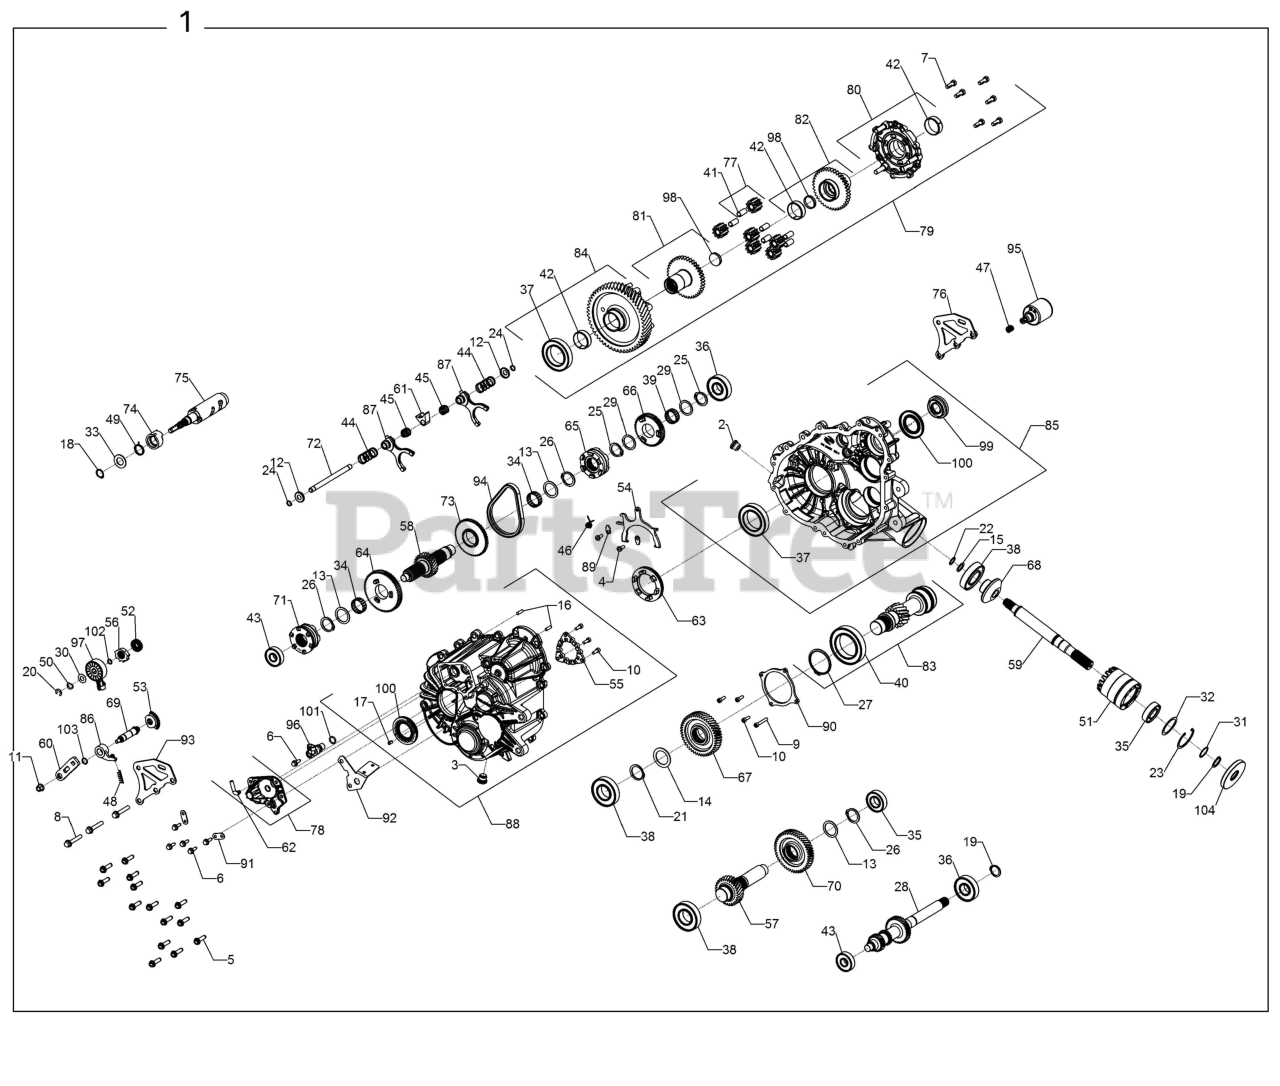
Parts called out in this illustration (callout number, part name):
1	ASM., MAIN GEARCASE
2	PLUG-SKT HD 1SO 6149,M18 X 1.5
3	PLUG-SOCKET HEAD W/MAG,M18X1.5
4	SCREW, TORX PAN HD M6 X 1 X 16
5	SCREW-HEXFLANGEHEAD,M8X1.25X30
7	SCREW-CAP HH,M8 X 1.25 X 20
9	SCR-M6X1.0X40,SOC/CAP(105344)
10	SCR-SCKT HD,CP,M6X1X18(105355)
11	NUT-M8X1.25,HXFLG,NYLN(110093)
12	WASHER-CUP
16	PIN, DOWEL, 6 X 20
17	SPRING-SLOTTED PIN,6MM
18	RING, RETAINING BASIC EXTERNAL
19	RING, SNAP
20	RING-RETAINING
21	RING,RETAINING
22	RING,RETAINING,EXTERNAL SHR-66
23	RING,RETAININGBASICINTRNL2.047
24	RING-RETAINING
25	RING,RETAINING
26	RING, RETAINING, EXTERNAL
27	RING, RETAINING
28	SHAFT-PINNION,INPUT,BOSS,LW
29	WASHER,THRUST
30	WASHER,THRUST,.446X.88X.025
31	SHIM 1.180 X .995
32	SHIM 2.040 OD X 1.630 ID
33	SPACER, 19.4 X 34 X 2
34	BEARING,NEEDLE
37	BEARING, BALL
38	BEARING-BALL
39	BEARING,NEEDLE
40	BEARING, BALL
41	BEARING,PLAIN,10X12X25
42	PLAIN,BEARING 40X44X15
43	BEARING, BALL
44	SPRING-COMPRESSION
45	SPRING-COMPRESSION
46	SPRING, TORSION RETURN
47	SPRING,COMPRSSN.54ODX.44IDX.05
48	SPRING, COMPRESSION DETENT
49	SPRING, TORSION
50	WASHER-SPRING,210393
51	TUBE, SNORKLE MACH
52	GEAR-SECTOR,16T
53	GEAR-SECTOR,31T-CUT TO 11T
54	SHIFT FORK (270507)
55	PARK PLATE (270509)
56	STAR, DETENT
57	SHAFT, IDLER, 29T
58	SHAFT,REVERSE,25T (285878)
59	SHAFT-FRONT OUTPUT(285914)
60	BELLCRANK
61	COLLAR-SHIFT
62	TUBE-VENT,90-1/4" HOSE
63	DOG-ENGAGEMENT
64	GEAR-LOW,67T(352856)
65	DOG, ENGAGEMENT, 6-FACE
66	GEAR, 53T
67	GEAR, 46T, STAGE 3
68	GEAR-13T,FRONT OUTPUT(352957)
69	SHAFT, SHIFT
70	GEAR,48T STAGE 2 (353115)
71	SHIFT DOG, PARK/LOW (353357)
72	RAIL-SHIFT SHAFT(353622)
73	SPROCKET, 48T, 6-FACE
74	PARK CAM
75	DRUM, SHIFT MACH
76	WELD-REAR MOUNT BRKT
77	GEAR SUBASSEMBLY
78	SUBASSY COVER, SECTOR GEARS
79	DIFF-LOCKING (411600)
80	SUBASSY-COVER,DIFF (411601)
81	SUBASSY-GEAR,39T SIDE (411607)
82	SUBASSY-GEAR,39T SIDE (411608)
83	ASM-SUB,PINION SHAFT(411759)
84	SUBASSY-GEAR,53T (411797)
85	SUBASSY,LH CASE(411919)
86	ROLLER PAWL
87	SUBASSEMBLY, SHIFT FORK
88	SUBASSEMBLY RH COVER
89	RETAINER-FORK
90	COVER, BEARING, CENTER DRIVE
91	BRKT-MOUNT(430592)
92	BRKT-MNT,HARNESS
93	BRKT-REAR MOUNT
94	CHAIN, SILENT
95	SOLENOID
96	SENSOR-SPEED,TRANS
97	SWITCH, ROTARY 2 PIN RESISTIVE
98	PLUG,EXPANSION,1 1/4
100	SEAL-TRIPLE LIP,VITON,40X70X7
101	O-RING, -113
104	SEAL-TRIPLE LIP 25X80X10
